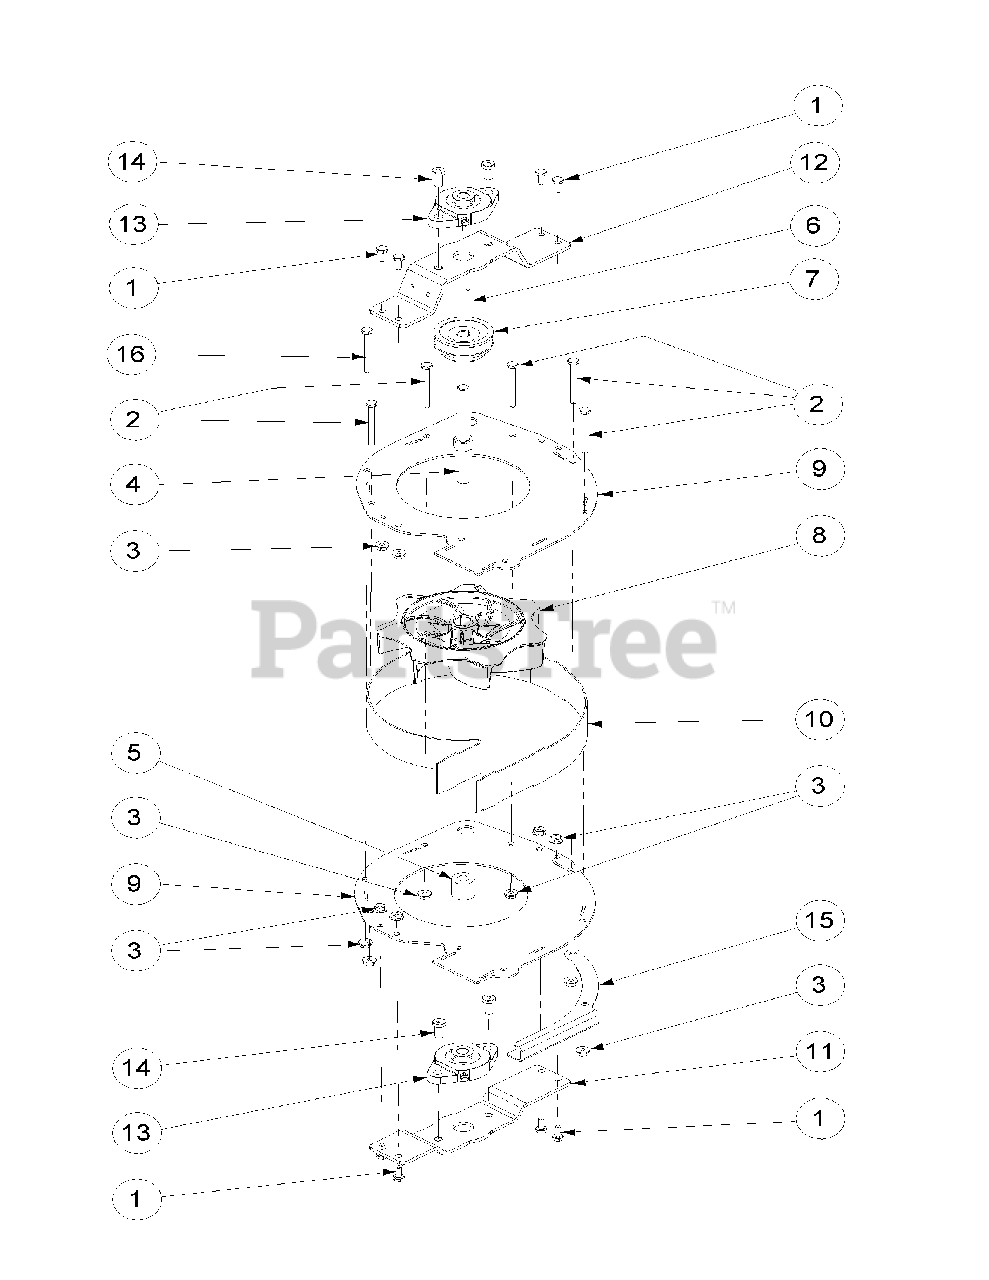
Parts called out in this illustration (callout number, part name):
1	HHCS, 1/4-20 x 0.620
2	HHCS, 1/4-20 x 2.50
3	Hex Nut Flange Lock, 1/4-20
4	Blower Shaft
5	Blower Spacer
6	Key, 1/8 x 1/8 x 1.00
7	Cast Pulley, .500 ID x 2.50 OD
8	Blower Impeller
9	Blower Housing Cover
10	Blower Housing Band
11	Bottom Bearing Mounting Plate
12	Top Bearing Mounting Plate
13	Flange Bearing
14	Socket Head Screw, 3/8-16 x .75
15	Guard Deflector
16	HHCS, 1/4-20 x 2.75
